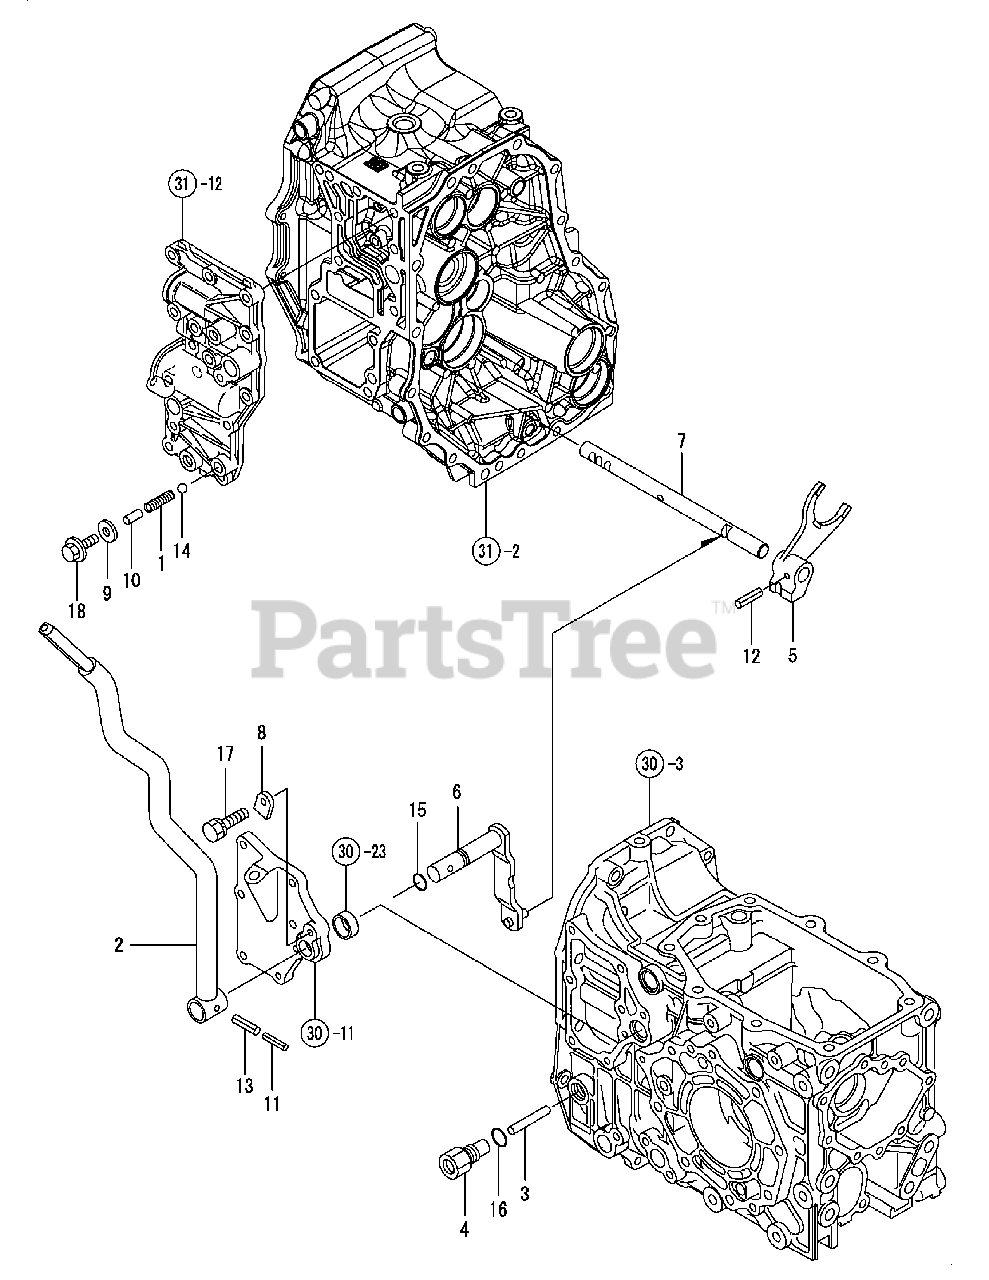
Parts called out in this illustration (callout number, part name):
3	Pin,Switch Renge
5	Fork,Shift Renge
7	Shaft, Range Fork
9	Seal Washer 10(Bolt)
10	Parallel Pin, M8X16
11	Spring Pin 3.5X32
12	Spring Pin 6X25
13	Spring Pin 6X32
14	Ball 5/16, Steel
15	O-Ring 1A P-12.5
16	O-Ring 1A P-14.0
18	Bolt M10X 25 Plated
